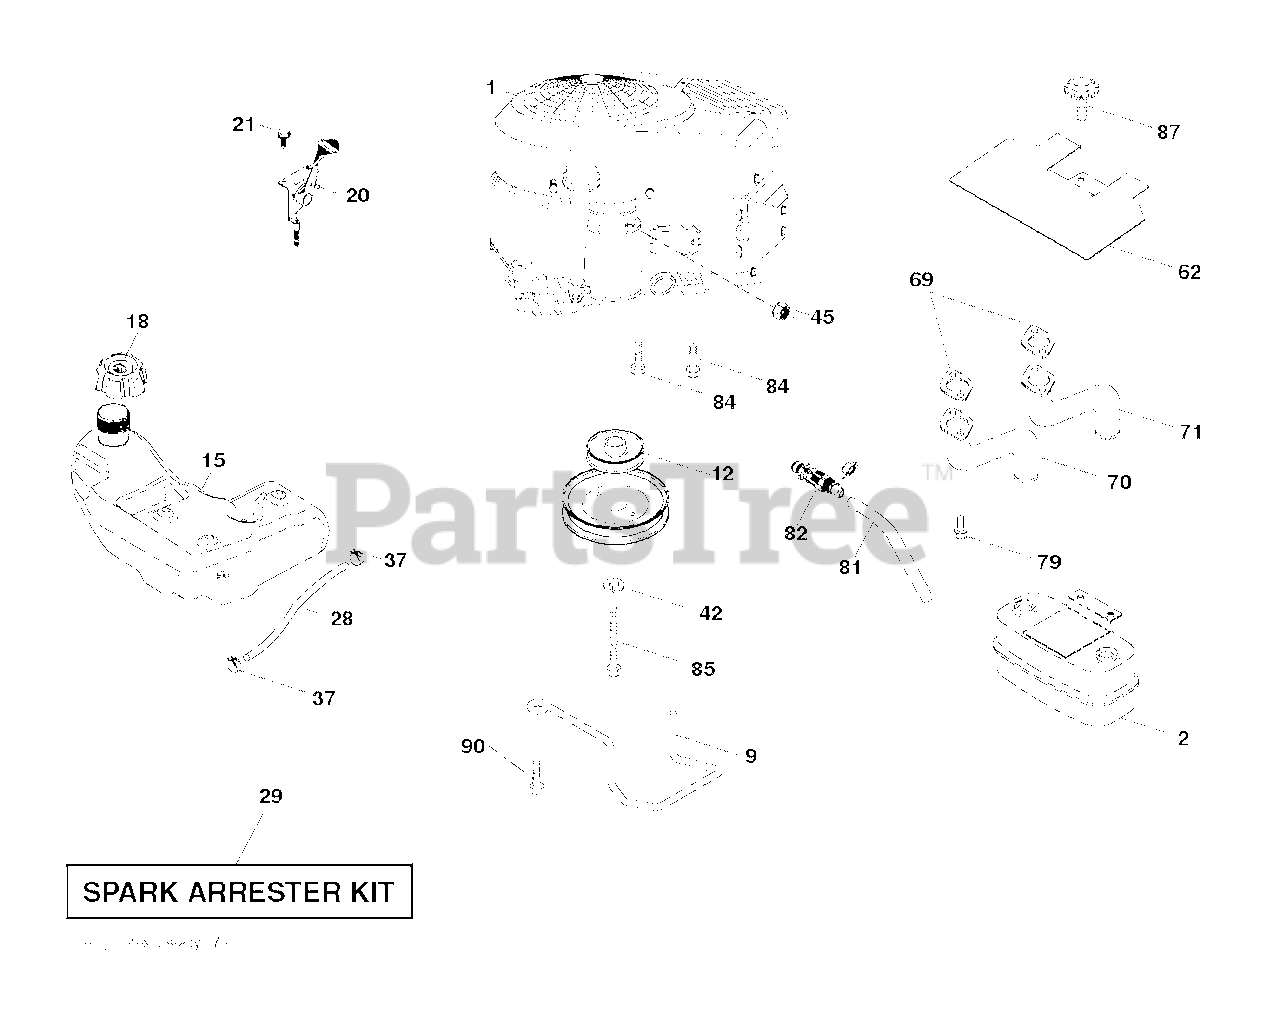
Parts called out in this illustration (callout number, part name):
2	MUFFLER.TWIN.CYL.LOW.TONE
9	KEEPER.BELT.ENGINE.4.2
12	PULLY ENGINE
15	TANK.ASSY.3.GAL.EPA
18	CAP ASM.FL.RTCHT.3"GRY.E10
20	CONTROL.TH/CK.COBRA.B&S.TWN.
21	SCREW.#10 X 0.750.BOS (2 2)
28	LINE.FUEL.64"REAR.EMIS
29	KIT.SPARK ARRESTOR(392390 B&S)
37	HOSE CLAMP
42	LOCKWASHER
45	NUT
62	SHIELD.HEAT.MUFFLER
69	GASKET.MUFFLER
70	RP.EXHAUST.TUBE.LH.BS/TWIN
71	RP.EXHAUST.TUBE.RH.BS/TWIN
79	SCREW.SOCKET.HEAD.5/16-18
81	TUBE, DRAIN OIL ASM.
82	VALUE.OIL.DRAIN
84	SCREW.3/8-16
85	BOLT HEX 7/16-20X4-1/4"
87	BOLT, 5/16-18 X 1 3/4
90	SCREW 3/8-16X1
